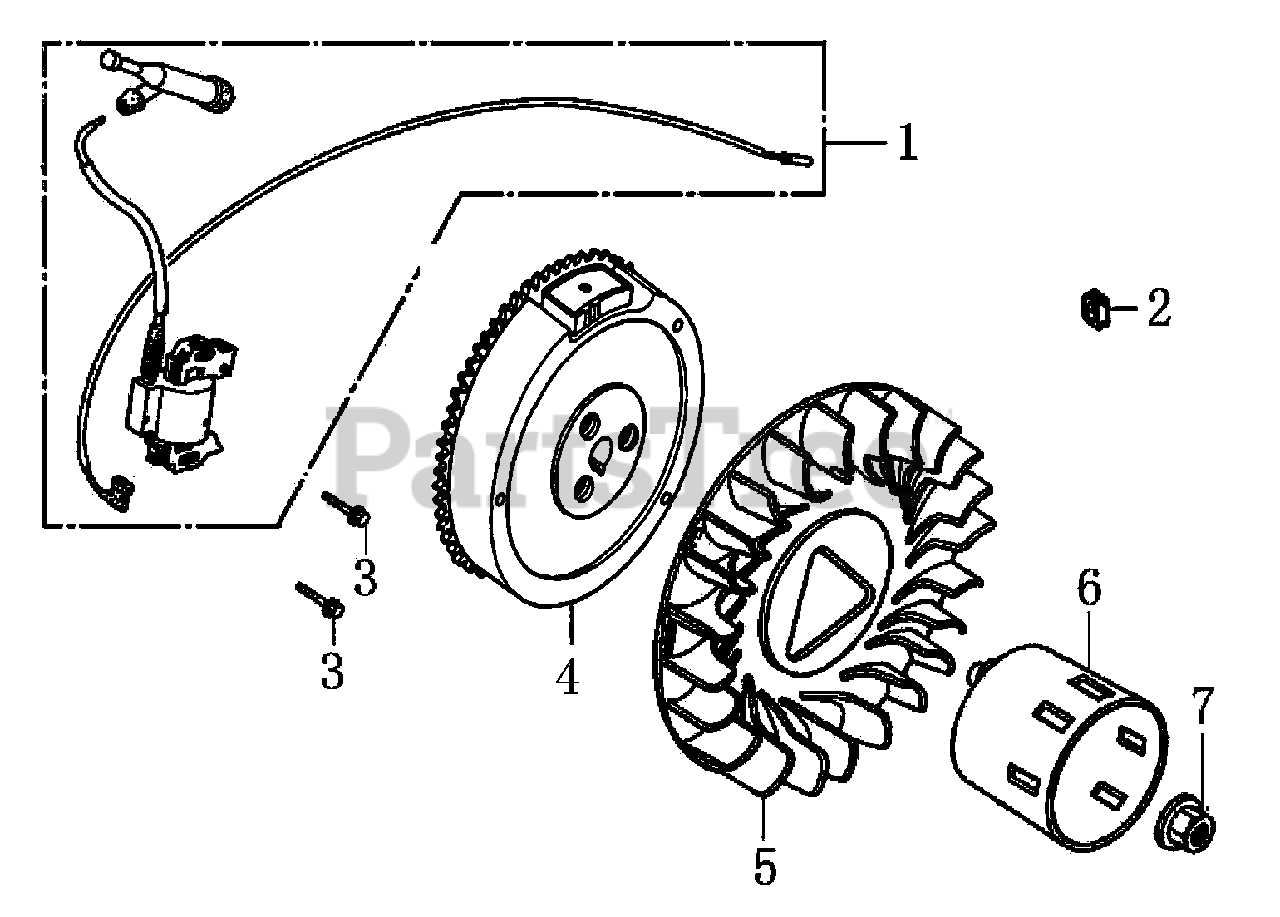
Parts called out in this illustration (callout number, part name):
1	COIL ASSY. , IGNITION
2	GROMMET, CORD
3	BOLT, FLANGE, M6X25
4	FLYWHEEL, (ELECT. START) COMP.
5	FAN, COOLING
6	PULLEY, STARTER
7	NUT SPECIAL, 16MM
